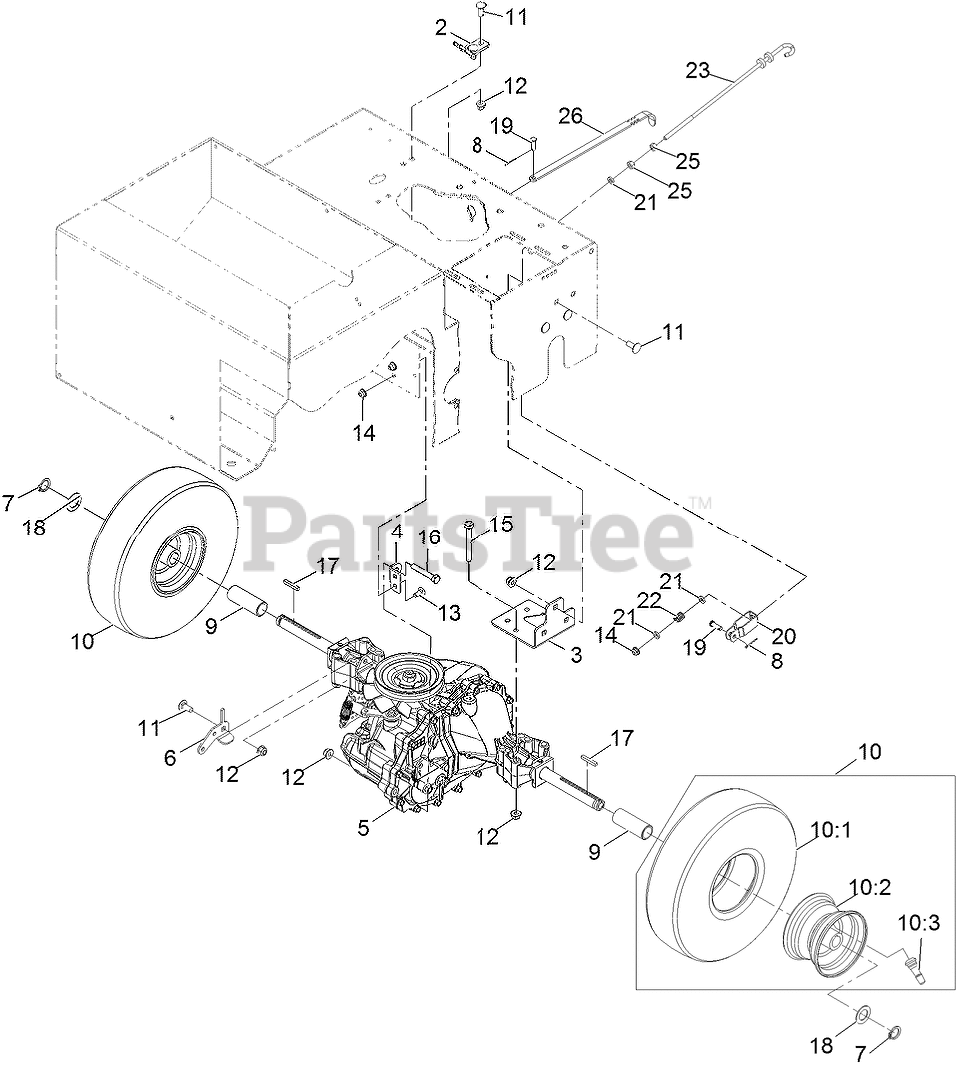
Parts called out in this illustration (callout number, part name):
2	BRACKET-CABLE
3	BRACKET-AXLE
4	BRACKET-TRANSAXLE, TORQUE
5	TRANSAXLE ASM
6	BRACKET-TRANSAXLE
7	RING-RETAINING
8	PIN-COTTER
10	WHEEL ASM
10:2	WHEEL-RIM
10:3	VALVE
11	SCREW-CARR
12	NUT-HF, NI
13	SCREW-CARR
15	SCREW-HH
16	SCREW-HH
17	KEY-SQUARE
19	PIN-CLEVIS
21	SPACER-PLATE, PIVOT
22	SPRING-COMPRESSION
23	ROD-BRAKE
25	NUT-HEX
26	LEVER-BYPASS
